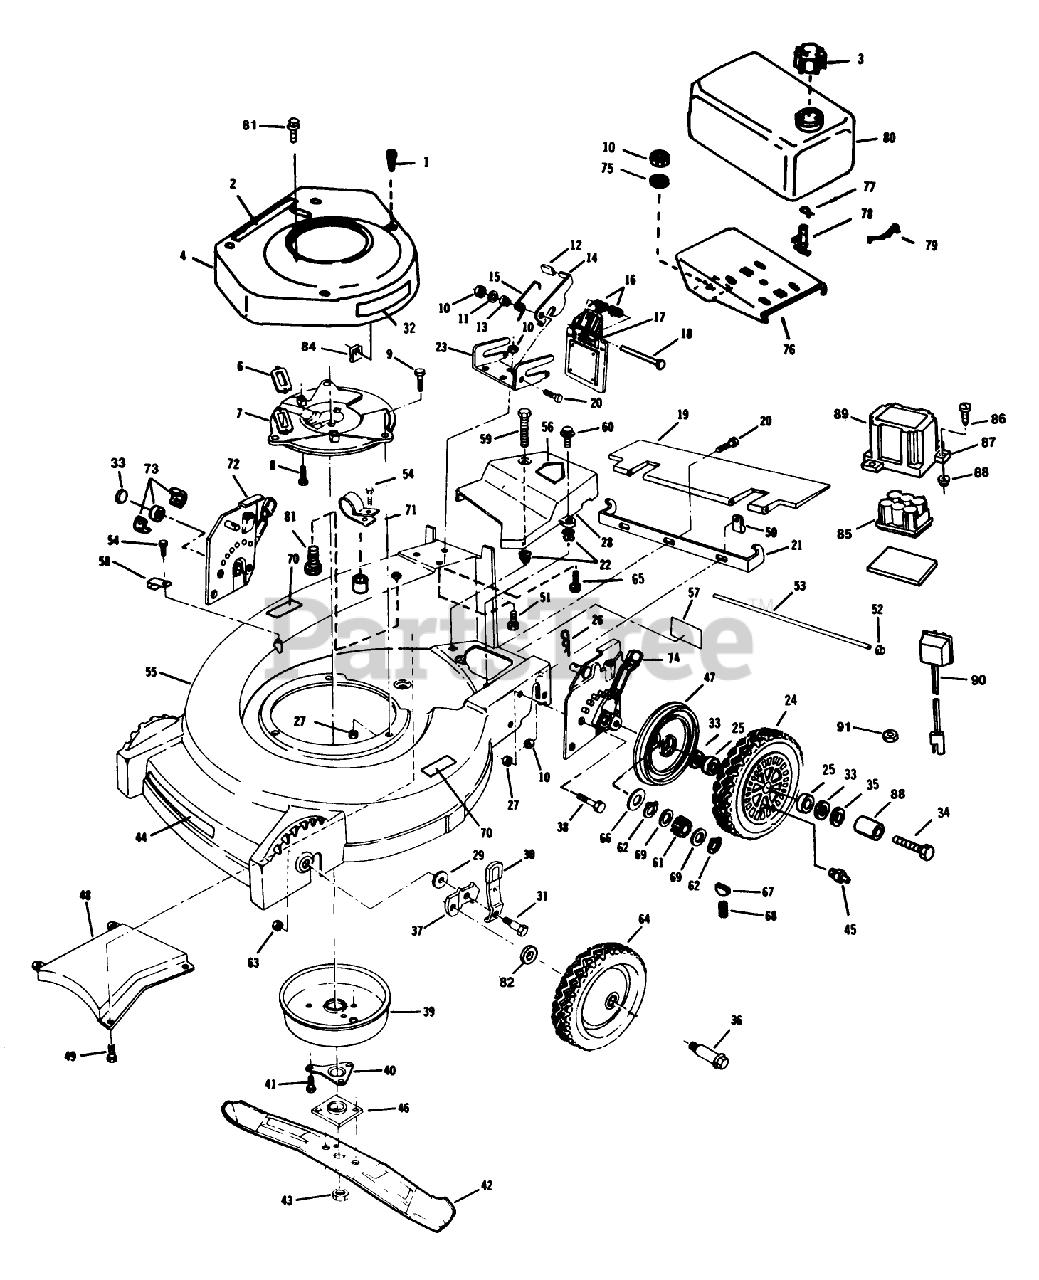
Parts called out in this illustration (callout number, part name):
1	SCREW - SELF TAPPING
3	FUEL CAP & INSERT
8	SCREW V
9	SCREW-HH
10	LOCKNUT E
12	KNOB (S&R)
15	SPRING
16	SPRING ASOC
18	ROD (RB&W)
19	T/SHIELD SM&P
26	HAIR PIN
27	NUT-LOCK F
29	WASHER
30	SPRING ARM ASM
31	BOLT
33	WASHER
35	SPACER
36	BOLT-SHOULDER
39	MUFFLER COVER F
40	SUPPORT F
41	SCREW
43	NUT-BLADE
44	DISCOUNTED
45	FITTING LINCOLN
46	PLATE AND COLLAR ASM
48	BAFFLE CHUTE PL
51	SCREW
54	SCREW LAWRENCE
60	SCREW
61	PINION BROCKWAY
62	RET RING
63	LOCKNUT
65	SCREW HEX WASHER
66	THRUST WASHER
67	KEY
68	SPRING
69	SPACER/GR ALGHNY
73	REAR AXLE BEARING
75	WASHER
77	CLAMP - HOSE S
78	VALVE&SCREEN SM
79	SPRING
81	SCREW - SELF TAPPING
82	WASHER WROUGHT
84	PUSHNUT F
86	SCREW - SELF TAPPING
87	NUT-CLIP
88	PAD-BATTERY
91	BASE SHROUD F
